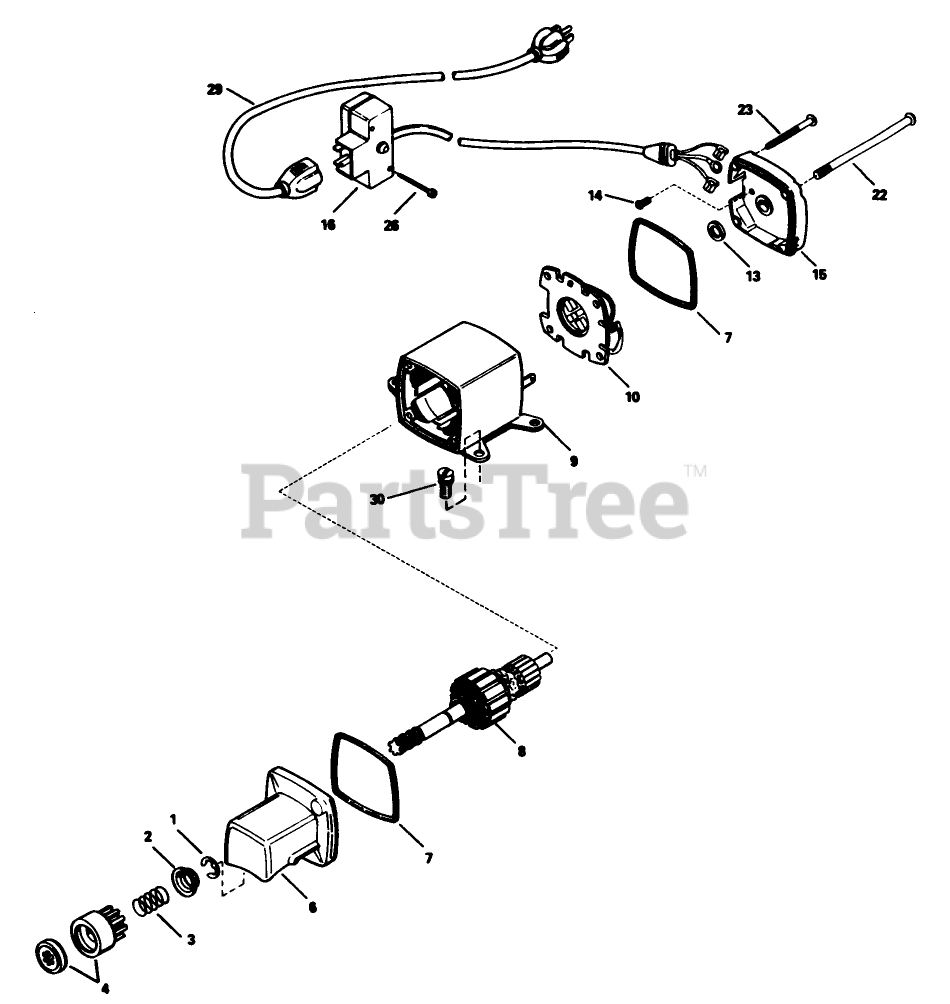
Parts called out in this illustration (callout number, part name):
1	Retainer-Ring
2	Retainer-Spring
3	Spring-Anti Drift
4	Nut Gear
6	Cap Assembly (Incl. Ref. #7)
7	O-Ring
8	Armature
9	Housing Assembly
10	Card ASM
13	Washer-Thrust
14	Screw-Ground
15	Cap Assembly (Incl. Ref. #7)
16	Box Assembly-Switch (Incl. Ref. #26)
22	Bolt-Case
23	Screw-Ground
26	Screw
29	Cord-Extension
30	Screw (T-30, 1/4-20 x 23/32)
